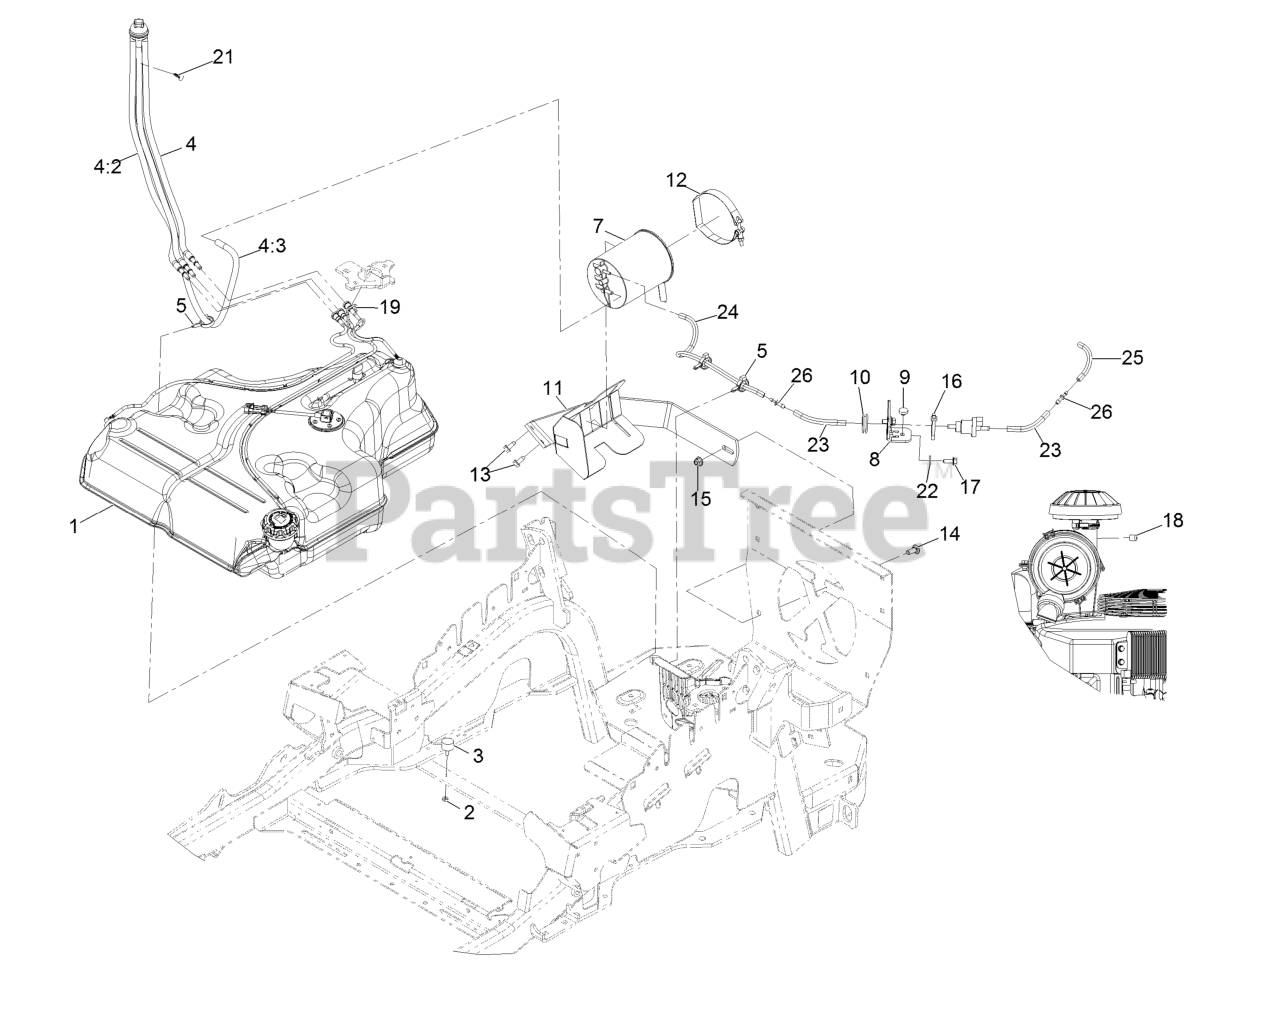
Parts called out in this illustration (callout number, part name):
1	FUEL TANK ASM
2	NUT-JAM
4	FUEL MANIFOLD VENT ASM
4:2	HOSE-FUEL
4:3	HOSE-FUEL
5	CLAMP-HOSE
7	CANISTER-CARBON, 1200CC
8	BRACKET-VALVE MOUNT
10	GROMMET
11	MOUNT-CANISTER
12	CLAMP, T-BOLT
13	Screw-HWH 5/16-18 X 3/4 Tf
14	SCREW-CARR
15	NUT-HF, NI
16	TIE-PLASTIC
17	SCREW-HHF
18	PLUG-PORT
19	RETAINER-LINE, VAPOR
21	PLUG-PLASTIC
22	WASHER-SPRING
23	HOSE-FUEL
24	HOSE-FUEL
25	Hose-Fuel
26	FITTING-STRAIGHT
